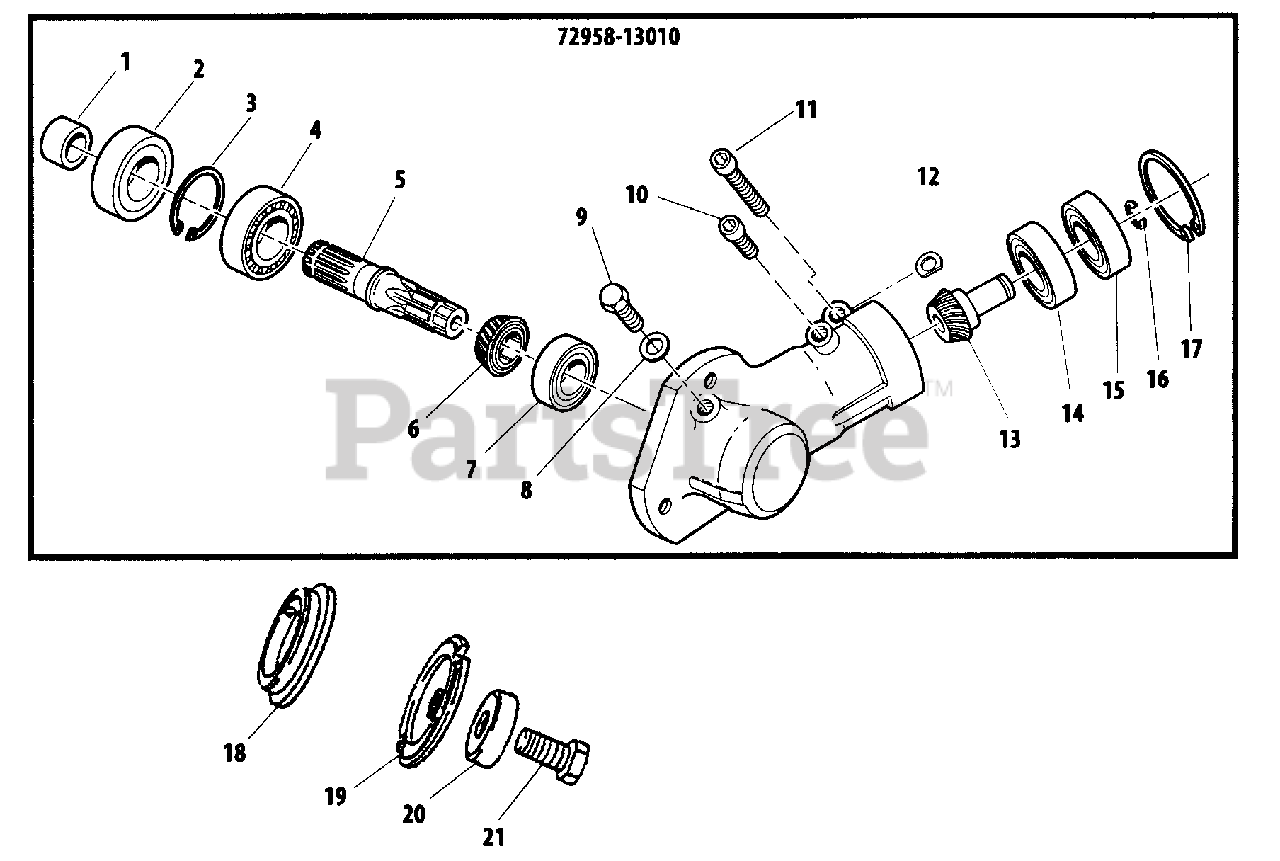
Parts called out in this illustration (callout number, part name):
1	COLLAR
2	SEAL, OIL
3	RING, RETAINING - 28
4	BEARING, BALL - 6001
5	GEAR - SHAFT
6	GEAR - BEVEL
7	BEARING, BALL - 608DDU
8	WASHER - 6
9	BOLT - 6X10
10	SCREW - 5X16
11	SCREW - 5X25
12	SHIM
13	GEAR - SHAFT
14	BEARING, BALL - 609
15	BEARING, BALL - 609ZZ
16	RING, RETAINING
17	RING, RETAINING - 24
18	HOLDER - A
19	HOLDER (B)
20	GUARD
21	BOLT - 8 -- LEFT HAND
72958-13010	GEAR CASE ASSY
